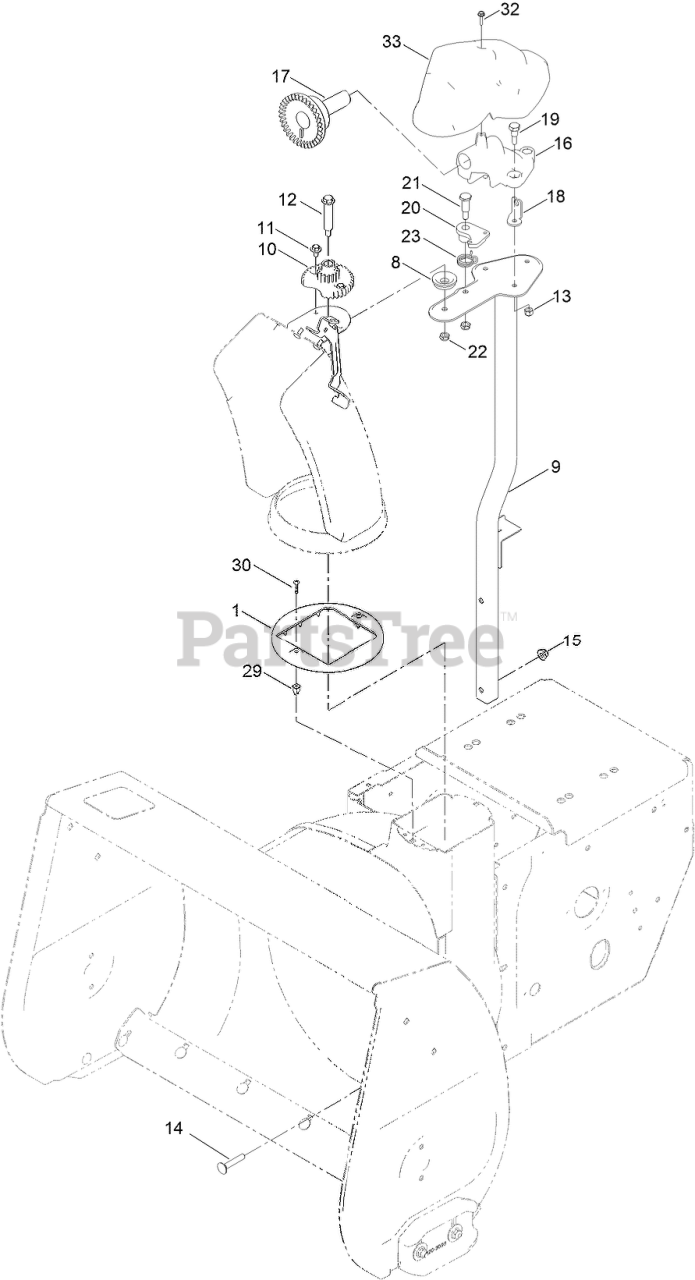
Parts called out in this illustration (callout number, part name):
1	GUIDE-CHUTE
8	SPACER-CHUTE
9	CHUTE POST ASM
10	GEAR-CHUTE
11	SCREW AND WASHER ASM
12	BOLT-SHOULDER
13	NUT-HEX
14	BOLT-CAR
15	NUT-HF
16	MOUNT-GEAR, FACE
17	GEAR-FACE
18	ANCHOR-CABLE
19	SCREW-SHOULDER
20	LATCH-CHUTE
21	SCREW-SHOULDER, HH
22	NUT-HEX
23	SPRING-TORSION
29	GROMMET-SCREW
30	SCREW-PPH
32	SCREW-PLASTITE, HWH
33	COVER-GEAR, FACE
